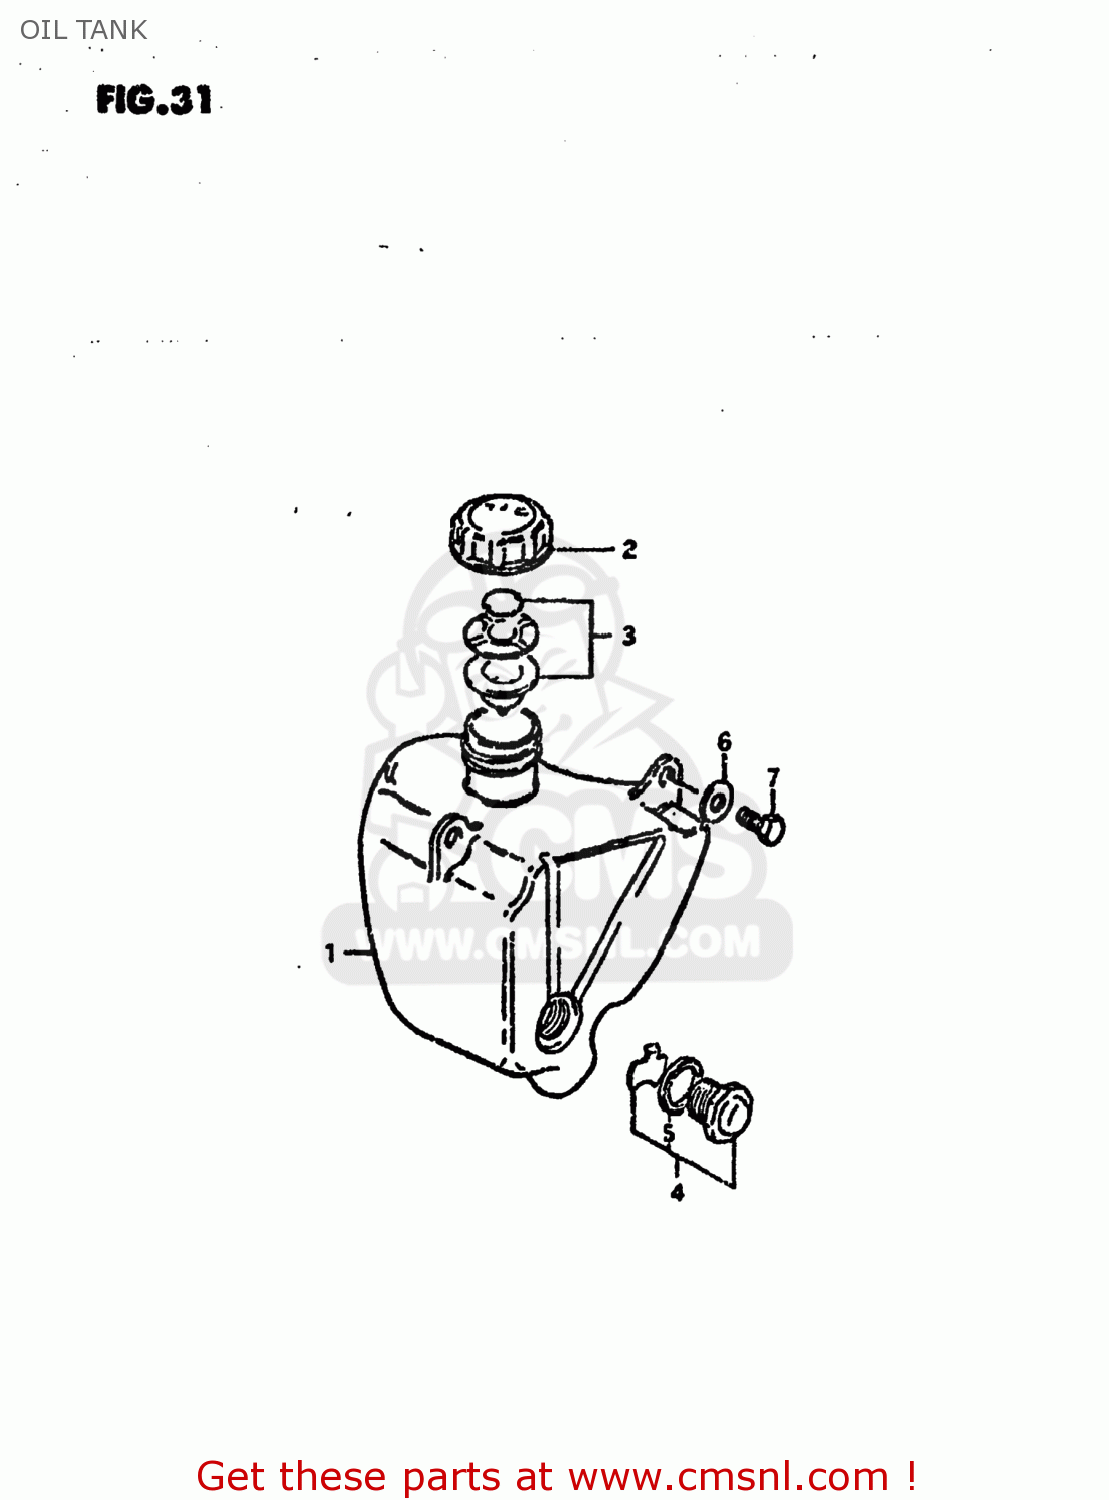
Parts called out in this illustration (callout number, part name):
1	TANK,OIL
2	CAP,OIL TANK
3	GASKET SET (NAS)
4	LENS SET,OIL LEVEL
5	GASKET (NAS)
6	WASHER
7	BOLT
